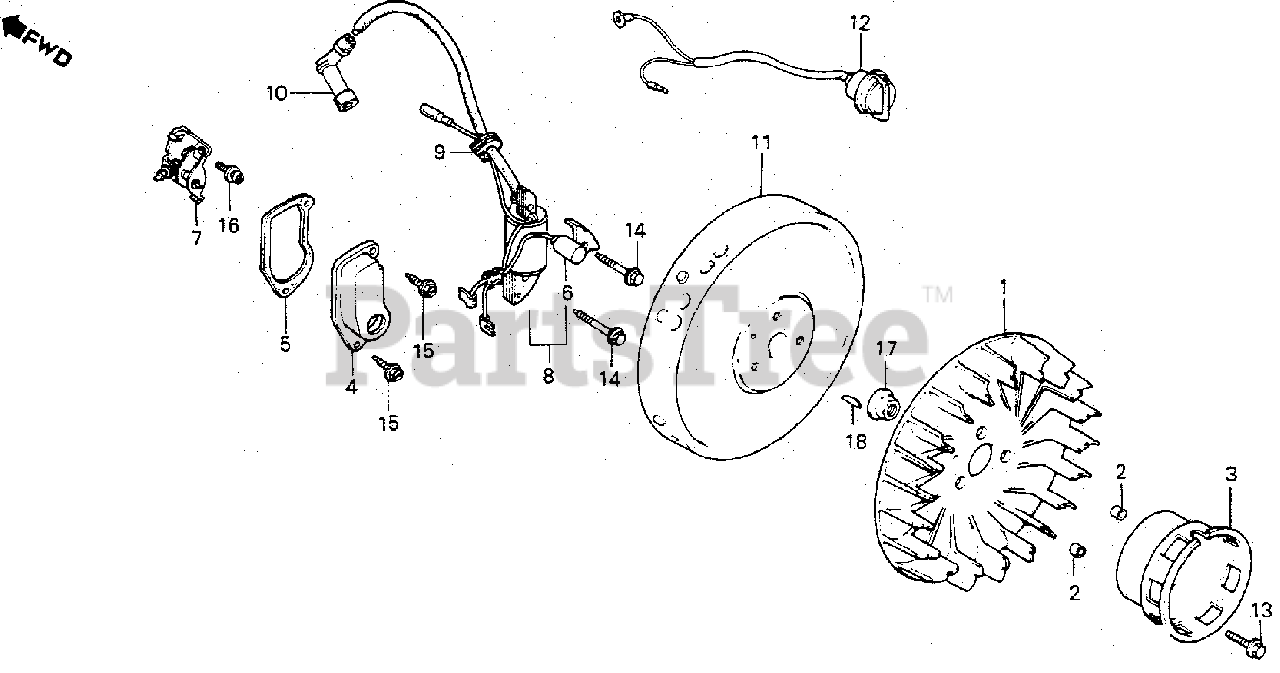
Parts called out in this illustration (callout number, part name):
1	FAN, COOLING
2	COLLAR, FAN
3	PULLEY, STARTER
4	COVER, POINTS
5	GASKET, POINT COVER
7	POINTS ASSY.
8	COIL ASSY., IGNITION
9	GROMMET, WIRE
10	CAP ASSY., NOISE SUPPRESSOR (NOT AVAILABLE)
12	SWITCH ASSY., STOP (NOT AVAILABLE)
13	BOLT, FLANGE (6X16)
14	BOLT, FLANGE (6X32)
15	BOLT, FLANGE (5X10)
16	SCREW-WASHER (5X12)
17	NUT, SPECIAL (14MM)
18	KEY, SPECIAL WOODRUFF (25X18)
